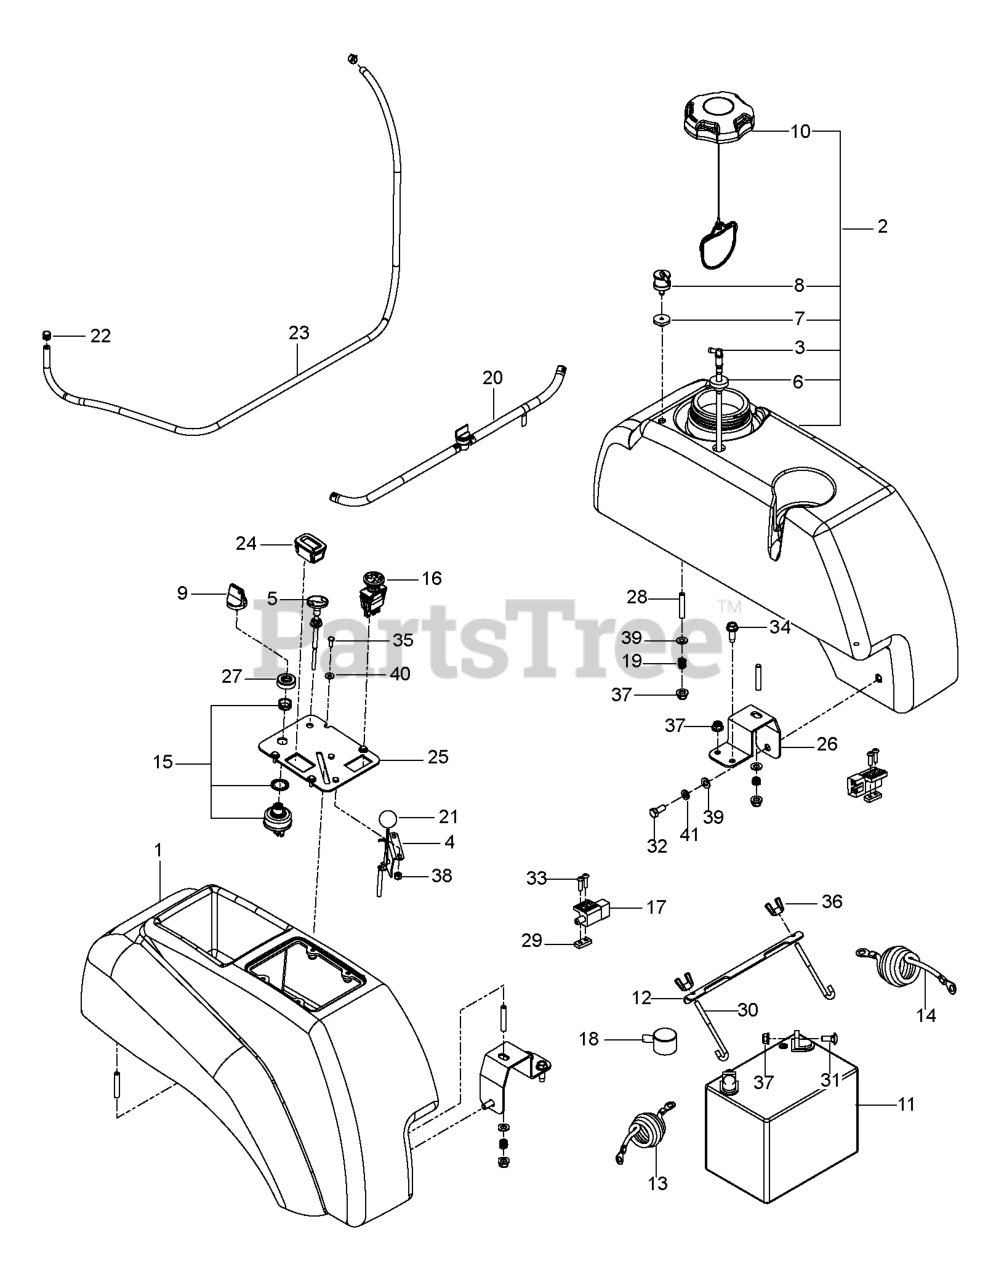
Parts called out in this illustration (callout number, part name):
1	FENDER CONSOLE
2	FUEL.TANK.ASSY.LH.MZ.GRY
3	FITTING, FUEL
4	THROTTLE CABLE
5	CABLE, CHOKE, 38
6	RUBBER GROMMET
7	GROMMET, CHECK VALVE
8	VALVE.FUEL.CHECK
9	KEY, IGNITION
10	CAP, FUEL
11	BATTERY, 12 V 330 AMP
12	BRACKET, BATTERY MOUNT
13	CABLE.BATT.SOLENOID.MZ.RED.25"
14	CABLE.GROUND.BATT.MZ.BLACK.39"
15	SWITCH, IGNITION, INDAK
16	RP SWITCH.PTO.TERMINAL.STD.RED
17	SWITCH INTERLOCKT
18	COVER.TERMINAL.BATTERY
20	FUEL.HOSE.SHUT.OFF.ASM.10".10"
21	KNOB.ROUND.BALL.BLACK
22	CLAMP, HOSE
23	HOSE.3/16".VAPOR.LINE.27"LGTH
24	GUAGE.SRVCMNDR.HRMTR.
25	PLATE, CONSOLE, BLK
26	SUPPORT, TANK, BLK
27	CAP IGNITION NUT
28	STUD, 5/16C
29	PLATE NUT ZTR
30	HOOK, "J"
31	RP BOLT 5/16-18 X3/4 ZN/YEL GR
32	BOLT.FIN.HEX.5/16-18X3/4
33	SCR #10-24 X .75 SKT HD BLK
34	SCREW
35	HCS #10-24 X 1/2
36	WING NUT 1/4
37	5/16-18 NYLOC FLANGE NUT
38	NUT 10-24 NYLOC
39	WASHER
41	WASH.5/16.SLW.ZD
